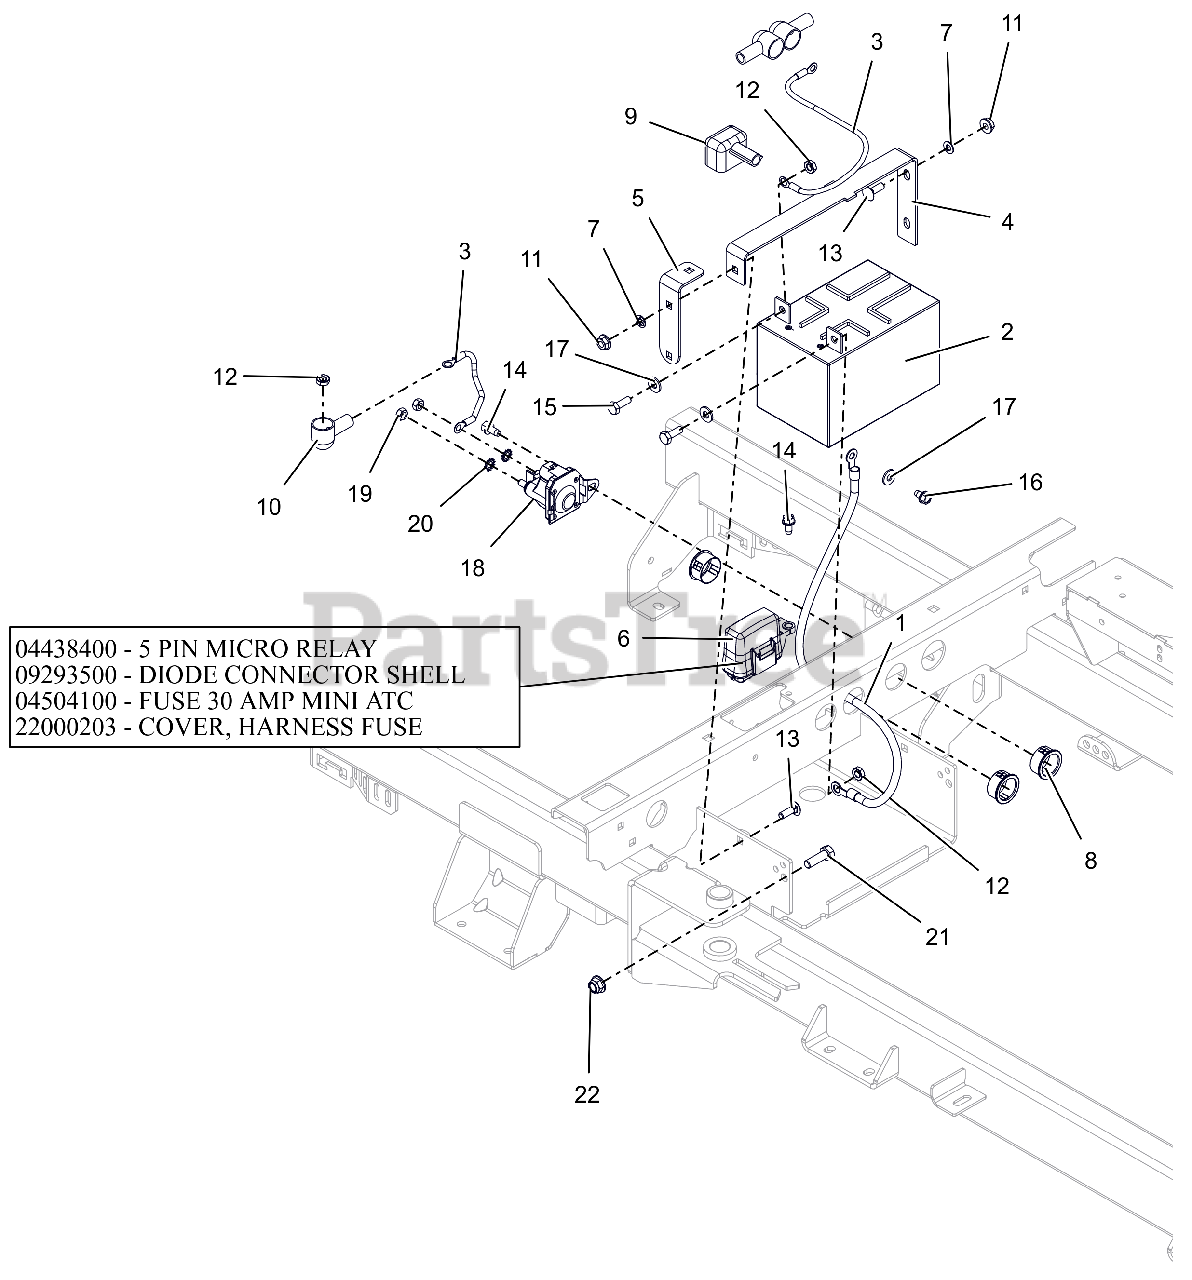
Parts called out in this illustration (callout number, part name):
1	CABLE-NEGATIVE BATTERY 24.00"
2	BATTERY, 12V 12A-190CCA
3	CABLE,POS W/2 1/4 RING 15.0 LG
4	BRKT, BATTERY HOLD-DOWN
5	BRKT, BATTERY HOLD DOWN
6	HARNESS, WIRE-4POS KEY IKON/ZT
6	RELAY,MICRO5 TERML W/RESISTOR
6	DIODE, CONNECTOR SHELL
6	FUSE,30 AMP MINI-ATC
6	COVER, FUSE
7	NUT-PUSH .25X.50 O.D.
8	BSHG, PANEL SNAP .937X1.11X.56
9	INSULATOR
10	BOOT, EYELET TERMINAL
11	NUT-LK-TOP-FLG .250-20 GF ZCC
12	NUT-KEPS .250-20 ZCC
13	BLT, RHSN .25-20X.750 G5 ZCC
14	SCR-TAP .25-20X.50 HWH ZCC
15	BLT, HEX .25-20X.75 G5 ZCC
16	SCR,TAP .25-20X.375 HWH TR ZCC
17	WSHR,FLT .281X.625X.065 ZCC
18	SOLENOID, STARTER (SEALED)
19	NUT-STD M6-1.0 ZCC
20	WSHR,LK-EXT.262X.502X.026 ZCC
21	BLT,HEX .31-18X1.00 G5 ZCC
22	NUT,NYL-FLG .31-18 GF ZCC
